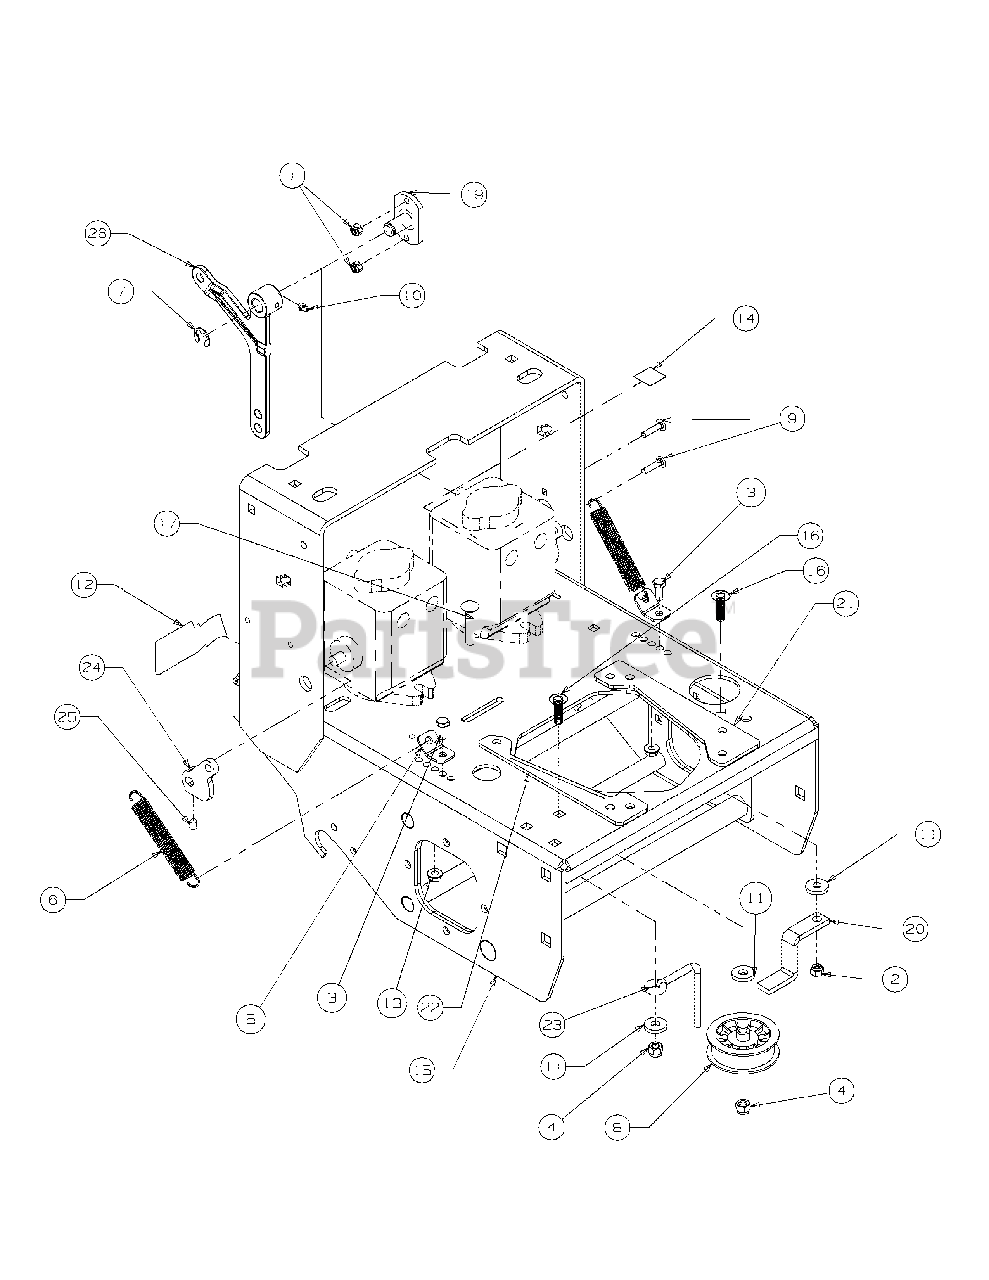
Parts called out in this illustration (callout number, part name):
1	Nut, L, Nylon Insert, 1/4-20 Grade A
2	Nut, 5/16-18, Nylock
3	Hex Cap Screw, 5/16-18 x .75
4	Nut, L, Nylon Insert, 3/8-16 Grade A
5	Mounting Bracket, Spring
6	Spring, Music Wire, LE-093G-9, Plated
7	E-Ring, 5/8" #5113-62
8	Pulley, Flat Idler W/Adaptor
9	Carriage Bolt, 1/4-20 x 1.00
10	Grease Fitting, 1/4-28 x 3/16 STR
11	Washer, Idler
12	Decal, "Made In America"
13	Lock Nut, 5/16-18, Hex Flange Lock
14	Label, Mower, Warn, Open Belt Drive
15	Engine Base Assembly, Hydro
16	Carriage Bolt, 3/8-16 x 1.25 Grade 5
17	Carriage Bolt, 3/8-16 x 2 Grade 5
19	Bellcrank Pivot Weldment
20	Belt Guide, Engine, 36/42/48
21	Spacer, Engine, Left Hand
22	Spacer, Engine, Right Hand
23	Belt Guide, 3.375
24	Pump Lever
25	Set Screw, 5/16-24 x 1.25
26	Bellcrank Clutch, Casting
